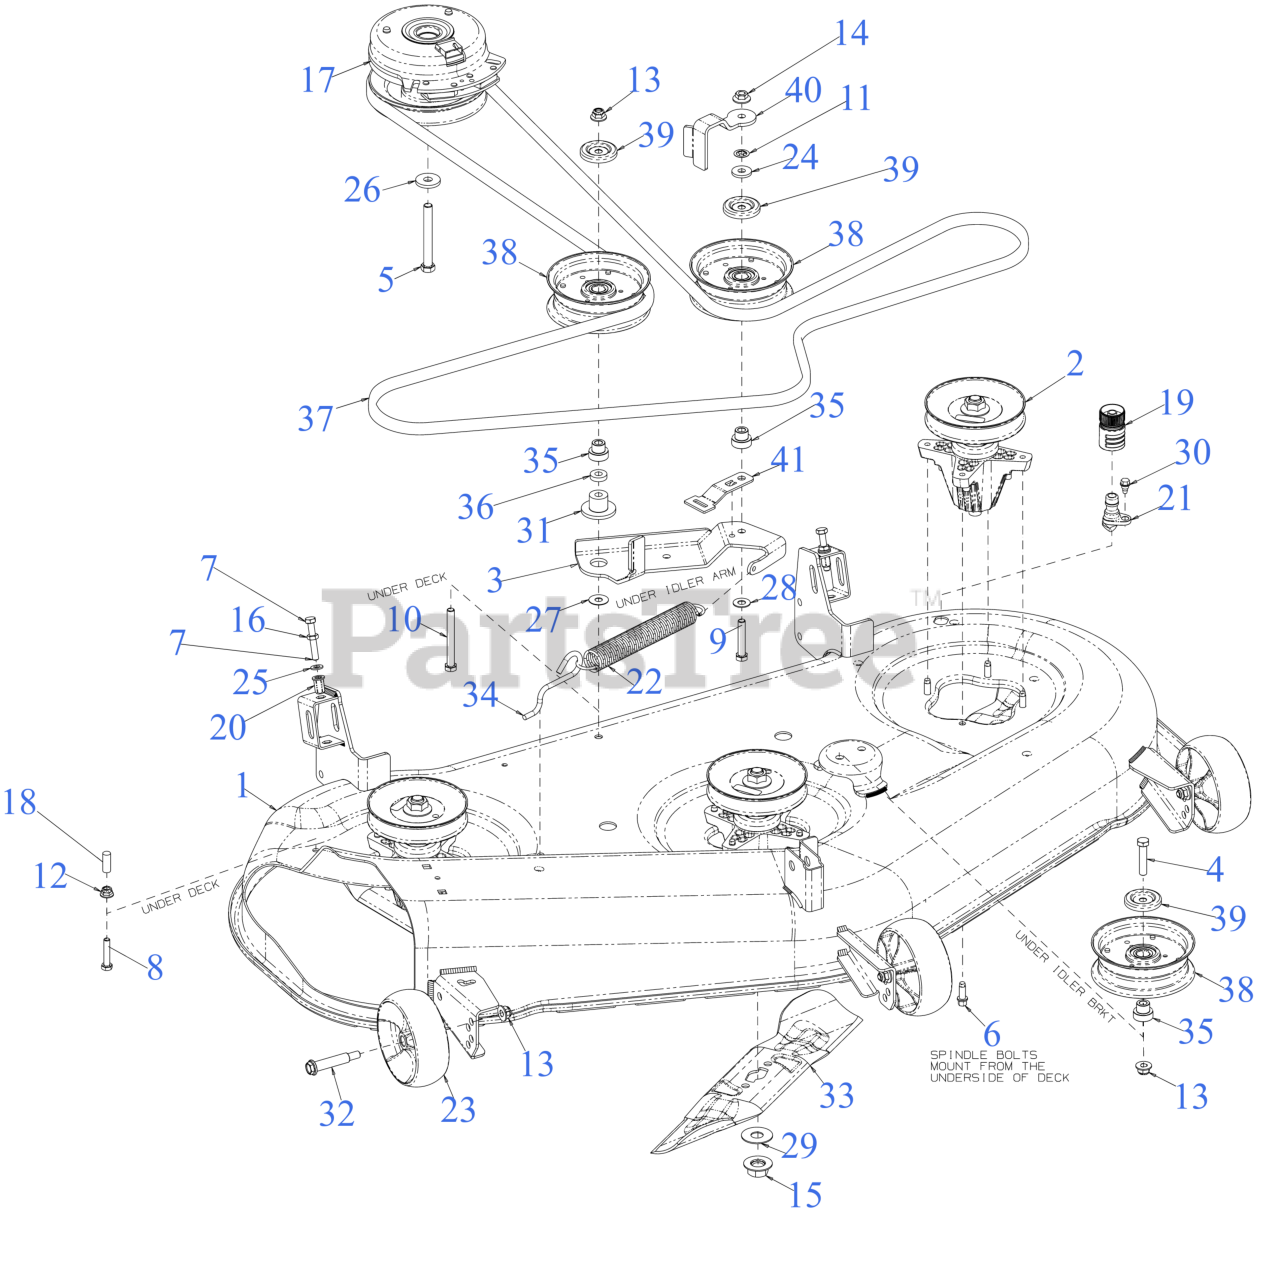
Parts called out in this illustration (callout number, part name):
1	50" DECK SHELL
2	SPINDLE ASSEMBLY (5.37 DIA)
3	DECK IDLER BRACKET
4	HEX SCREW 3/8-16 x 1.75 GR5
5	SCREW 7/16-20 x 3.5 GR5
6	SCREW 5/16-18 x .875
7	SCREW-FULL THREAD 5/16-18 GR5
8	SCREW 5/16-18 x 1.5 LG
9	SCREW 3/8-16 x 2.0 GR 8
10	SCREW 3/8-16 x 3.25 GR8
12	FLANGE LOCK NUT 5/16-18
14	FLANGE LOCK NUT
15	HEX FLANGE NUT 5/8-18 GR5
17	ELECTRIC PTO CLUTCH
19	WATER NOZZLE ADAPTER
20	NUT RIVET 5/16-18
21	DECK WASH NOZZLE
22	EXTENSION SPRING
23	DECK WHEEL (5.0 DIA x 1.875)
23	Cub Cadet 5" DECK WHEEL SET (06305A) (W/BOLT)
24	FLAT WASHER .385 x 1.00 x .135
25	FLAT WASHER
26	FLAT WASHER .445 x 1.248 x .170
27	FLAT WASHER
28	FLAT WASHER .401X.88
29	FLAT WASHER .635X1.585X.062 HDN
30	SHOULDER SCREW 1/4-20 x .50
31	SHOULDER SPACER
32	SHOULDER BOLT (.50 X 2.0 x 3/8 -16)
33	17.271" BLADE (2IN1) (S SHAPE CENTER HOLE)
33	Cub Cadet 50" HI LIFT BLADE SET (S SHAPE CENTER HOLE) (-05094)
33	Troy-Bilt 50" HI LIFT BLADE SET (S SHAPE CENTER HOLE)
33	17.271" XTREME BLADE (2IN1) (S SHAPE CENTER HOLE)
33	Cub Cadet 50" XTREME BLADE SET (S SHAPE CENTER HOLE) (-05094-X)
33	Troy-Bilt 50" XTREME BLADE SET (S SHAPE CENTER HOLE)
33	17.271" LOW LIFT (S SHAPE CENTER HOLE)
33	Cub Cadet 50" LOW LIFT BLADE SET (S SHAPE CENTER HOLE) (-05094-X)
33	Troy-Bilt 50" LOW LIFT BLADE SET (S SHAPE CENTER HOLE)
34	DECK SPRING HOOK
35	SHOULDER SPACER
37	V-BELT B SEC x 143.5 LG
37	Cub Cadet 50" DECK DRIVE BELT
37	Genuine Factory Parts 50" DECK BELT
38	IDLER PULLEY 4.50" DIA
39	IDLER PULLEY CAP
40	BELT KEEPER
